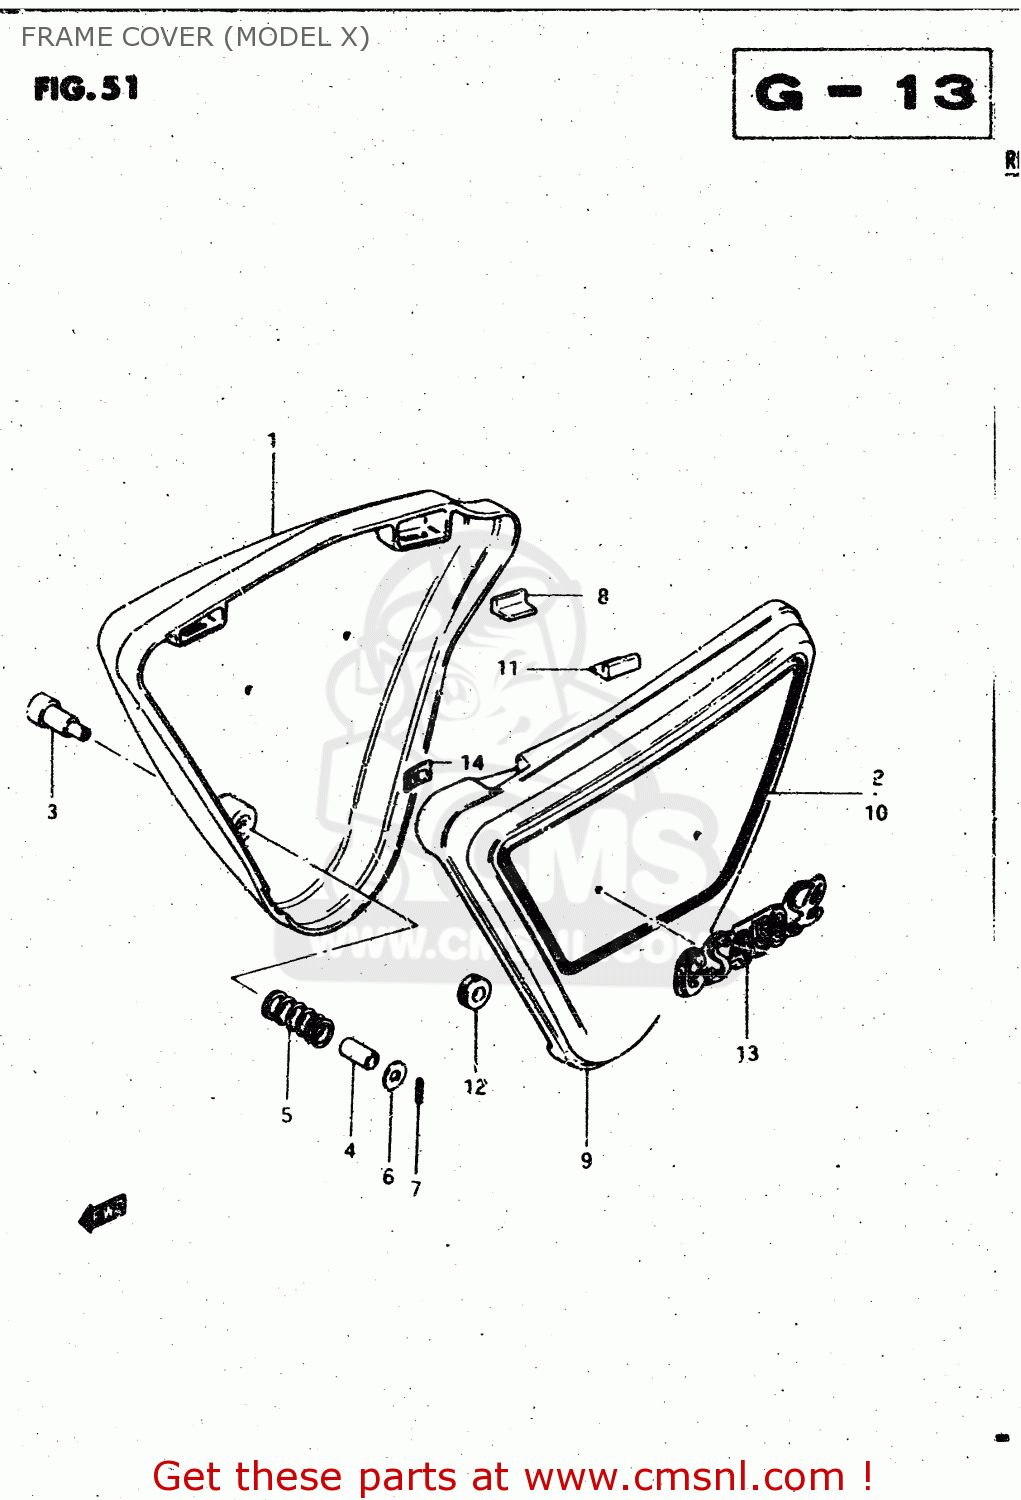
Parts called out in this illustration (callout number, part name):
1	COVER,FRAME,RIGHT
2	TAPE SET,FRAME COVER,RIGHT
3	KNOB,FRAME COVER,R
4	SPACER(14.9X17.3X13.5)
5	SPRING
6	WASHER (6.5X24X1.6)
7	PIN,SPRING(2.5X18)
8	CUSHION,FRAME COVER
9	COVER,FRAME,LEFT
10	TAPE SET,FRAME COVER,LEFT
11	CUSHION,FRAME COVER
12	CUSHION
13	EMBLEM
14	NUT
